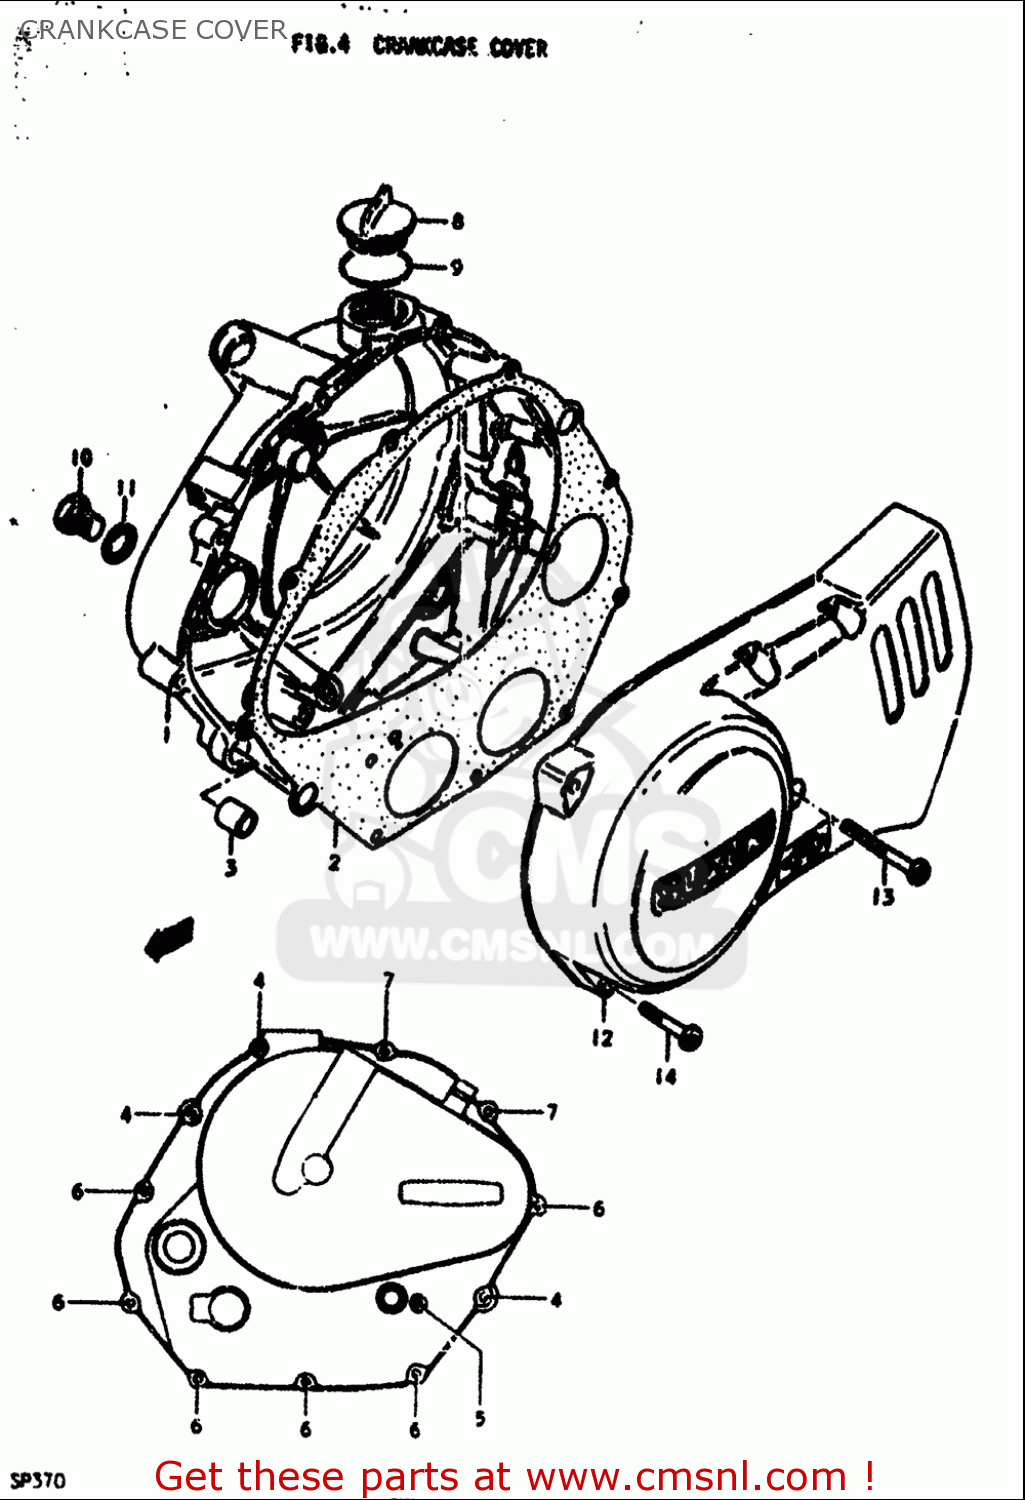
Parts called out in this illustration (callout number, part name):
2	GASKET,CLUTCH COVER (NAS)
3	PIN
4	SCREW
5	SCREW
6	SCREW
7	SCREW
8	PLUG SET
9	O RING(D:2.2,ID:32)
10	PLUG(14X12)
11	GASKET(14X19.2X2) (NAS)
13	SCREW
14	SCREW
